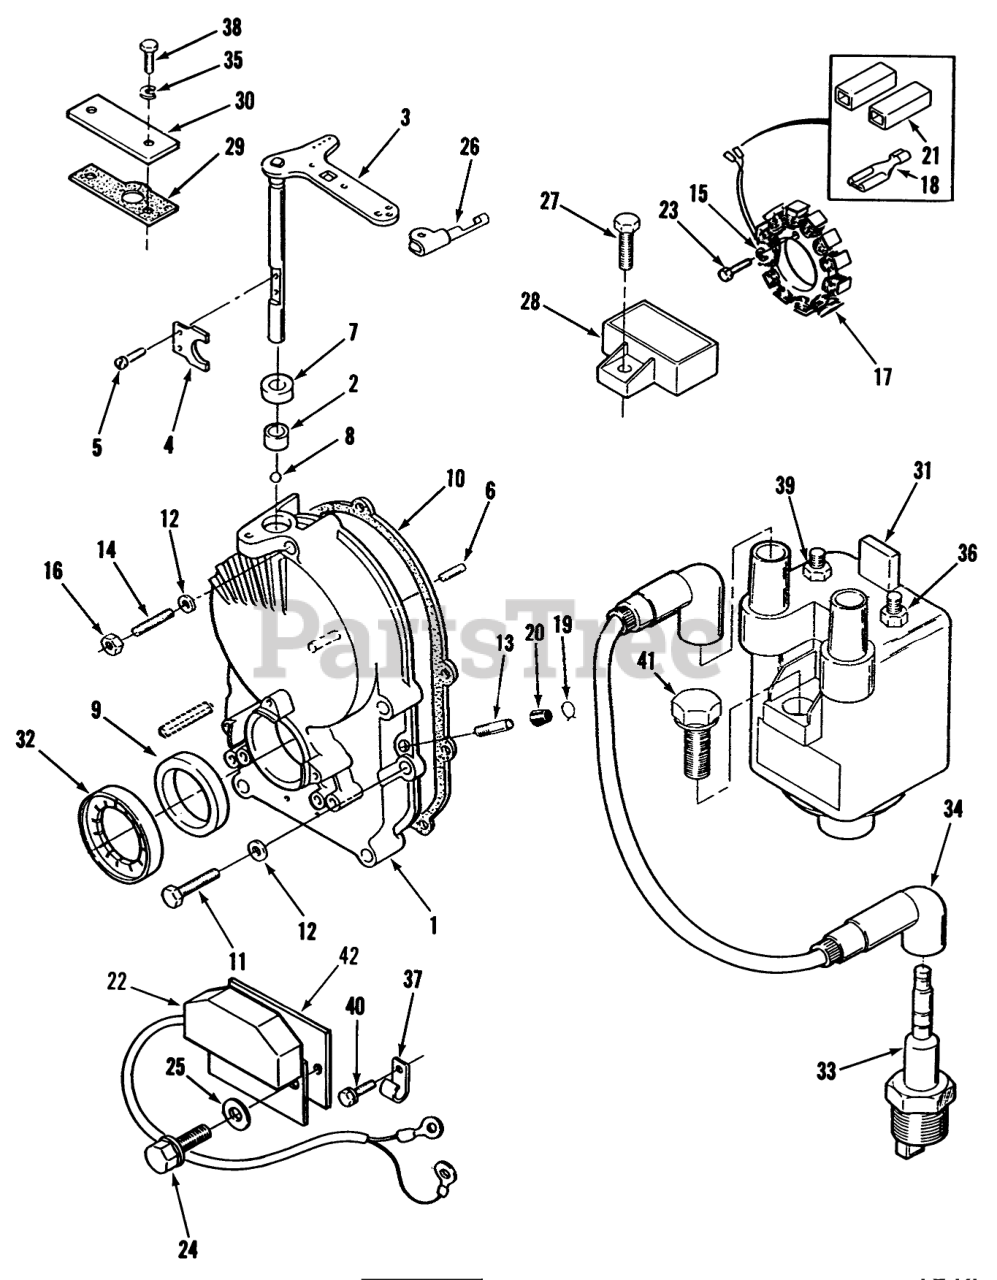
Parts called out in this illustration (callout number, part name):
1	Gearcase Kit (Includes Items 2 thru 9, 13, 19 & 20)
2	Bearing
3	SHAFT AND ARM
4	Yoke
5	Screw
6	Washer
7	Oil Seal
8	Bearing
9	Oil Seal
10	Gasket
11	Screw 5/16-18 1-3/4
12	Washer
13	Vacuum Tube
14	Stud
15	Lockwasher #10
16	Nut
17	Stator w/Terminals
18	Stator Leads Terminal
19	Clamp
20	Cap
21	Terrninal Connector Body Kit (Includes Terminals)
22	Control-Ignition
23	Bolt
24	Bolt
25	Lockwasher
26	Clip-Retaining
27	Bolt
28	Regulator
29	Gasket
30	Plate
31	Coil-Ignition
32	Rotor
33	Plug-Spark
34	Wire-Plug
35	Washer-Lock
36	Nut
37	Clip
38	Bolt
39	Nut
40	Screw-Cap Hex Hd.
41	Bolt
42	Insulator
